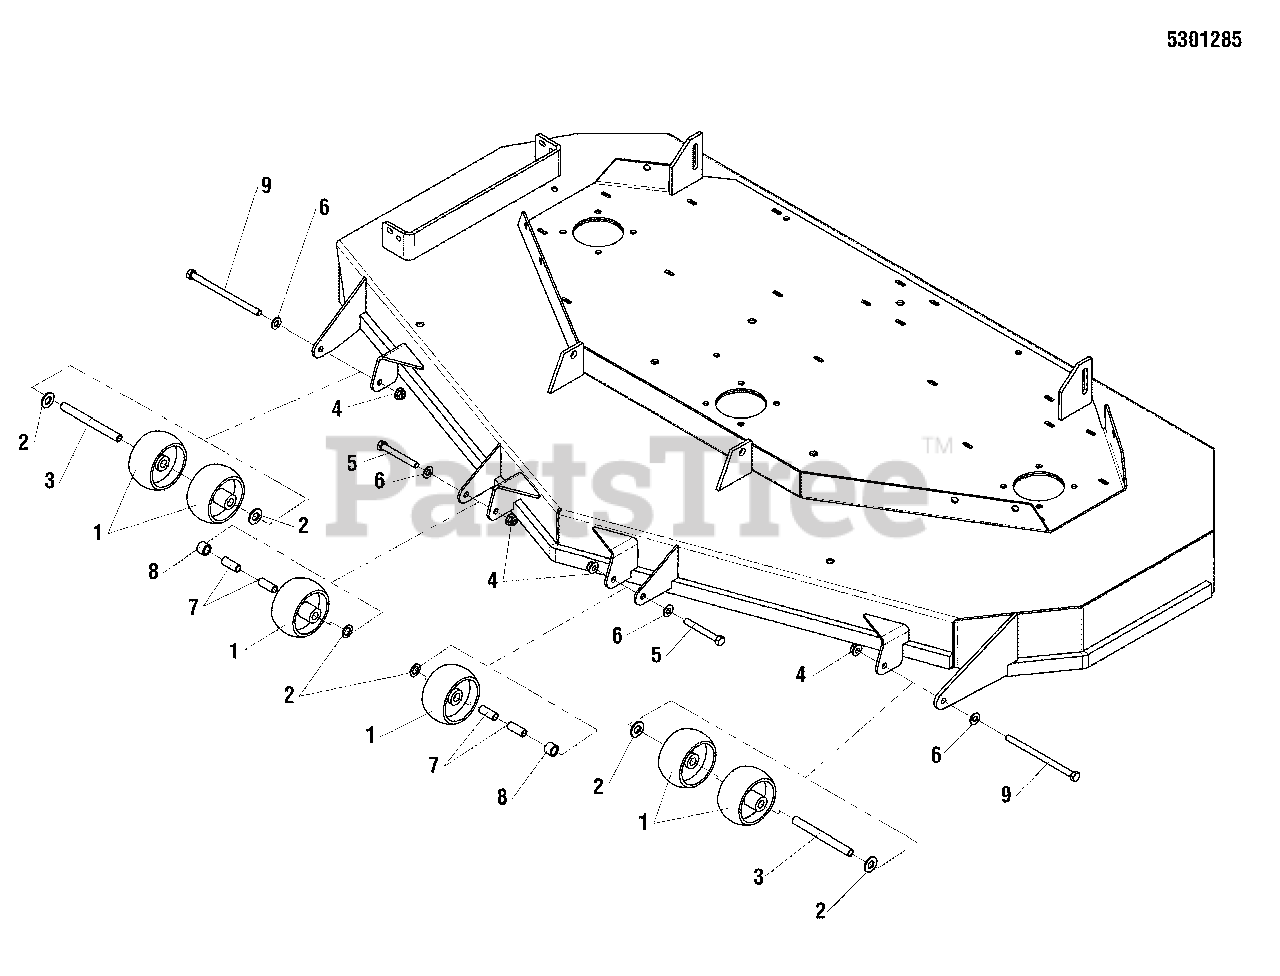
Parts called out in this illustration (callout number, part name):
1	WHEEL- 2.00 WIDE 3.88 DIA 0.531ID POLY
2	WASHER, 1/2 GD9 YZ
3	SPACER, .38 X .50 X 5.06
4	NUT, 3/8-16 HEX SIDE LOCK
5	BOLT, 3/8-16 X 3-1/2 GD5 YZ
6	WASHER, 3/8 SAE
7	SPACER, .38 X .50 X 1.25
8	SPACER, .51 X .75 X .56
9	BOLT, 3/8-16 X 6 GD5 YZ
